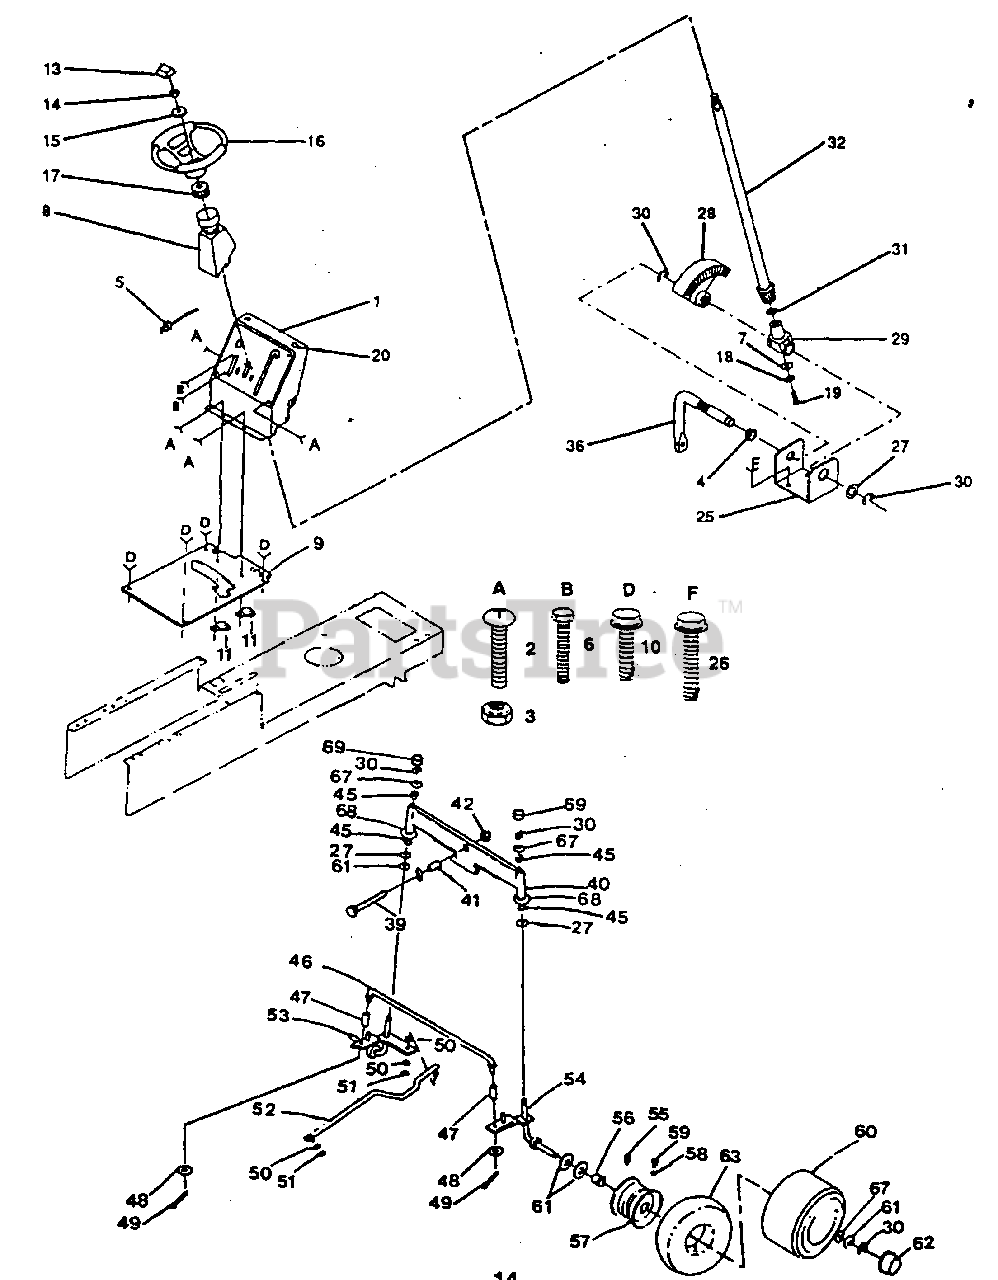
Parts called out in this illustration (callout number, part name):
2	Screw, Truss Head 5/16-18 x 3/4
3	Nut, Keps 5/16 - 18
4	Nyliner, Snap-in
5	Control, Throttle (AYP part number)
6	Screw, Hex, Thread Cutting 1/4 - 20 x 5/8 TY23
7	Washer 5/8 x 1/4 x 16 Ga. (AYP part number)
8	Boot, Steering
10	Screw, Hex, Washer Head Thread Rolling 3/8-16 x 1/2
11	Clip, Insulated (AYP part number)
13	Insert, Steering Wheel
14	Locknut, Hex, Jam 1/2 - 20
16	Wheel, Steering (AYP part number)
17	Adapter, Steering Wheel
18	Lockwasher 1/4
19	Screw, Socket Hex 1/4 x 20 x 5/8 (AYP part number)
20	Bumper, Hood
25	Bracket, Steering
26	Screw, Hex Washer Head, Thread Rolling 3/8- 16 x 3/4 Type TT
27	Bearing, Thrust
28	Gear, Sector (AYP part number)
29	Shaft, Support (AYP part number)
30	Ring, Klip
31	Washer
32	Shaft, Steering (AYP part number)
36	Shaft, Pitman (AYP part number)
39	Bolt, Hex 5/8-11 x 3-3/4
40	Axle, Front
41	Spacer, Bearing, Front Axle (AYP part number)
42	Locknut, Flange 5/8-11
45	Bearing (AYP part number)
46	Rod, Tie
47	Bushing (AYP part number)
48	Washer 13/32 x 7/8 x 16 Ga. (AYP part number)
49	Pin, Cotter 1/8 x 3/4
50	Washer, Lock 3/8
51	Nut, Hex 3/8 - 24
52	Link, Drag (AYP part number)
53	Spindle, L.H.
54	Spindle, R.H.
55	Fitting, Grease
56	Bearing, Flange
57	Rim, 6", Front (Inc. 2 Each Key No. 56) (AYP part number)
58	Cap, Valve
59	Stem, Valve
60	Tire (AYP part number)
61	Washer 25/32 x 1-1/4 x 16 Ga.
62	Cap, Axle (AYP part number)
63	Tube, Front (not furnished with tractor)
67	Washer 25/32 x 1-5/8 x 16 Ga.
68	Washer 27/32 x 1-1/4 x 16 Ga.
69	Cap, Spindle
